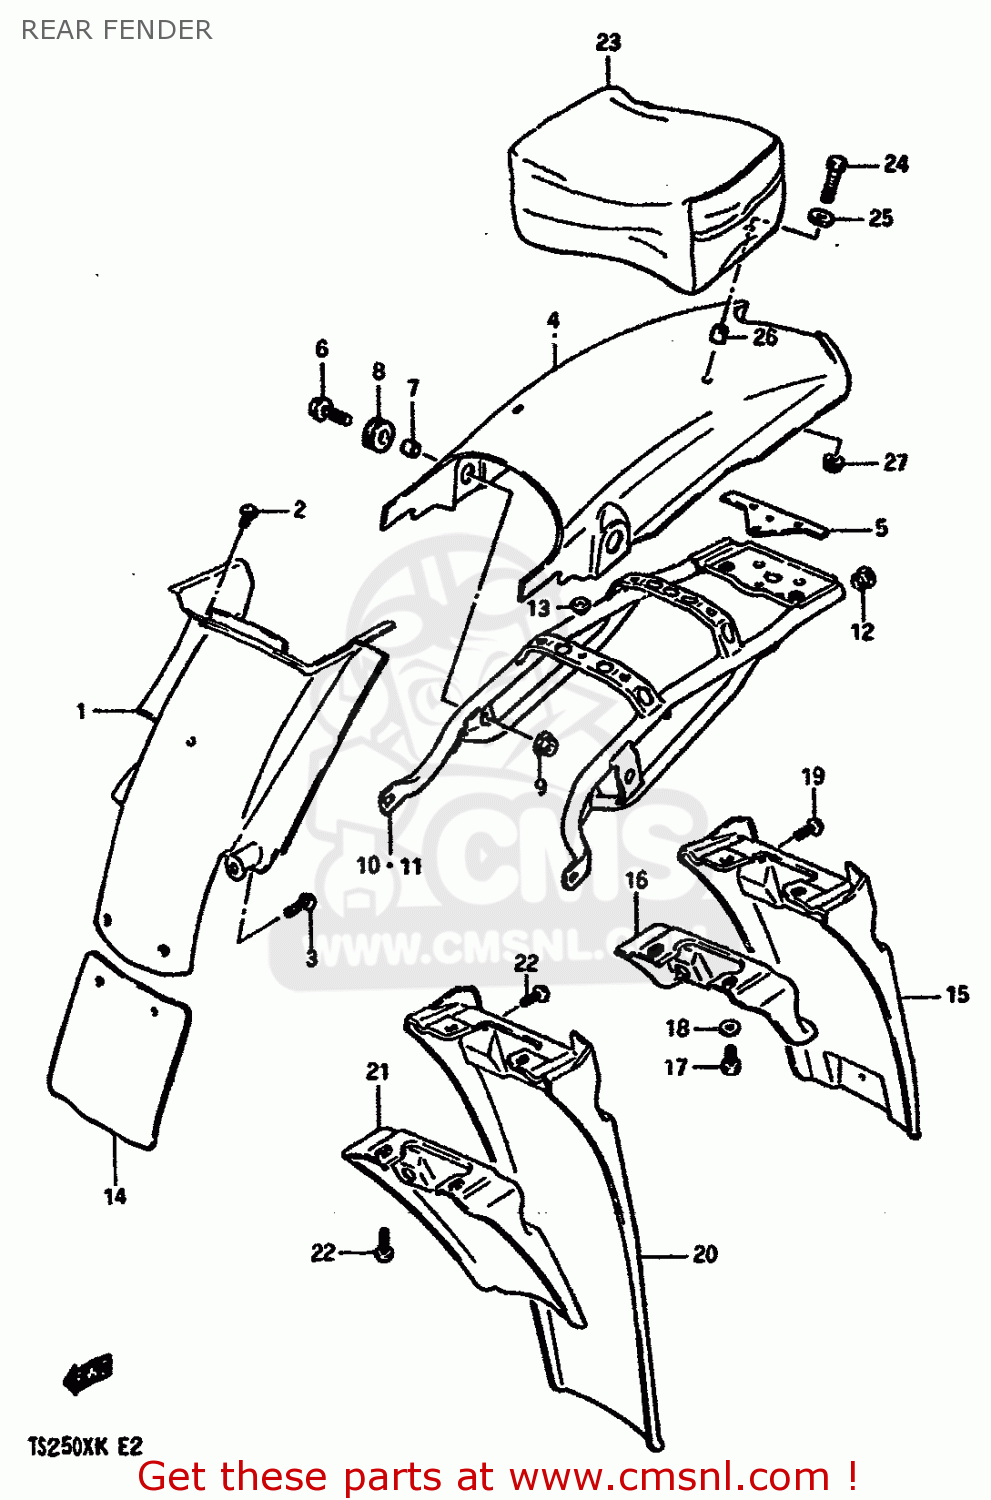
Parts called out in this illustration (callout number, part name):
1	BODY,REAR FENDER,FRONT
2	SCREW
3	SCREW
4	FENDER,REAR (WHITE)
5	CUSHION,RR FENDER
6	BOLT
7	SPACER (8.2X12X7.5)
8	CUSHION
9	NUT
10	REINFORCEMENT
11	REINFORCEMENT
12	CAP(OD:14)
13	CUSHION
14	MUD GUARD
15	EXTENSION
16	REINFORCEMENT
17	BOLT
18	WASHER (6.5X18X1.6)
19	SCREW
20	EXTENSION
21	REINFORCEMENT
22	SCREW
23	BAG ASSEMBLY,SEAT TAIL
24	BOLT
25	WASHER
26	SPACER (6.1X9X9)
27	NUT
